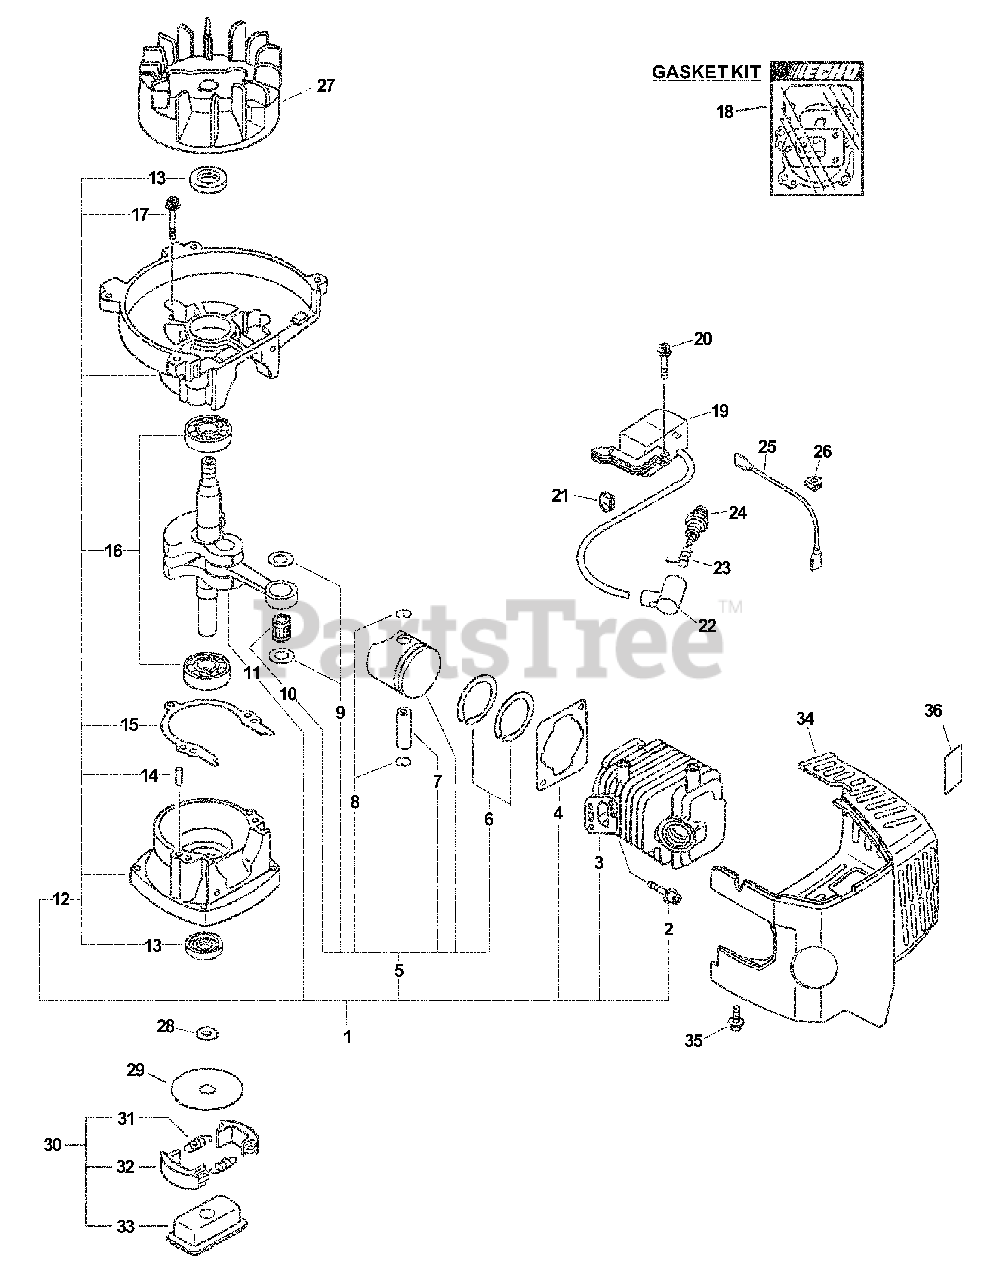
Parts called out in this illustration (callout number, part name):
1	SHORT BLOCK
2	BOLT 5×22
3	CYLINDER
4	GASKET, CYLINDER
5	PISTON KIT
6	RING, PISTON
7	PIN, PISTON 8
8	RING, SNAP
9	WASHER, THRUST
10	BEARING, NEEDLE
11	CRANKSHAFT ASSY
12	CRANKCASE KIT
13	SEAL, OIL 12
14	PIN, LOCATING 4
15	GASKET, CRANKCASE
16	BEARING, BALL - 6201 C3
17	BOLT 5×28
18	GASKET KIT
19	COIL, IGNITION
20	SCREW 4×22
22	CAP, SPARK PLUG
23	TERMINAL, SPARK PLUG
24	SPARK PLUG - BPM-7Y
25	LEAD
27	FLYWHEEL
28	WASHER, CLUTCH
29	PLATE, CLUTCH
30	CLUTCH ASSY
31	SPRING, CLUTCH
32	SHOE, CLUTCH
33	BOSS, CLUTCH
34	COVER, ENGINE
35	BOLT 4×20
36	LABEL, CAUTION - HOT
